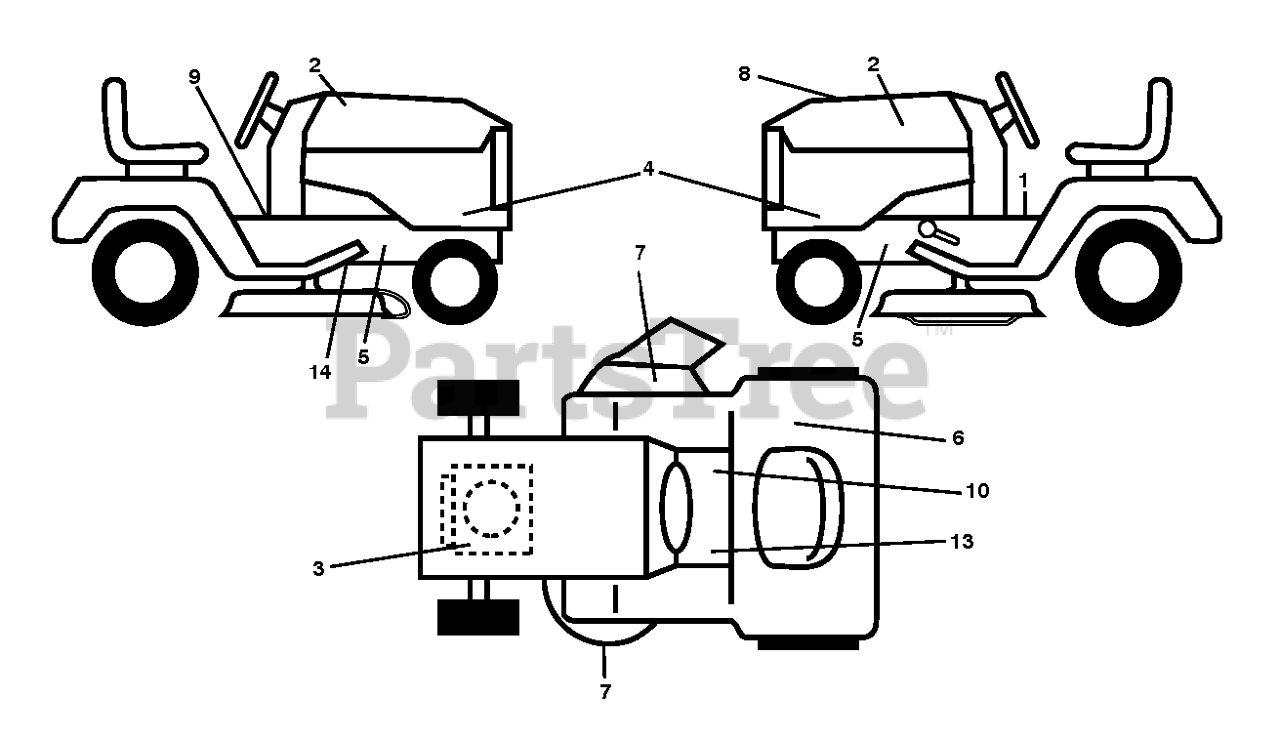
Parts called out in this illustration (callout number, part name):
1	LABEL
2	DECAL.BADGE.170MM.TEXTLOGO.
3	DECAL
6	Decal, Fender 100 DB/CE
7	DECAL.INTERNATIONL.CUTFINGER
9	DECAL
10	DECAL PARK BRAKE
13	DECAL
14	DECAL DECAL V-BELT 97 CM CRD
